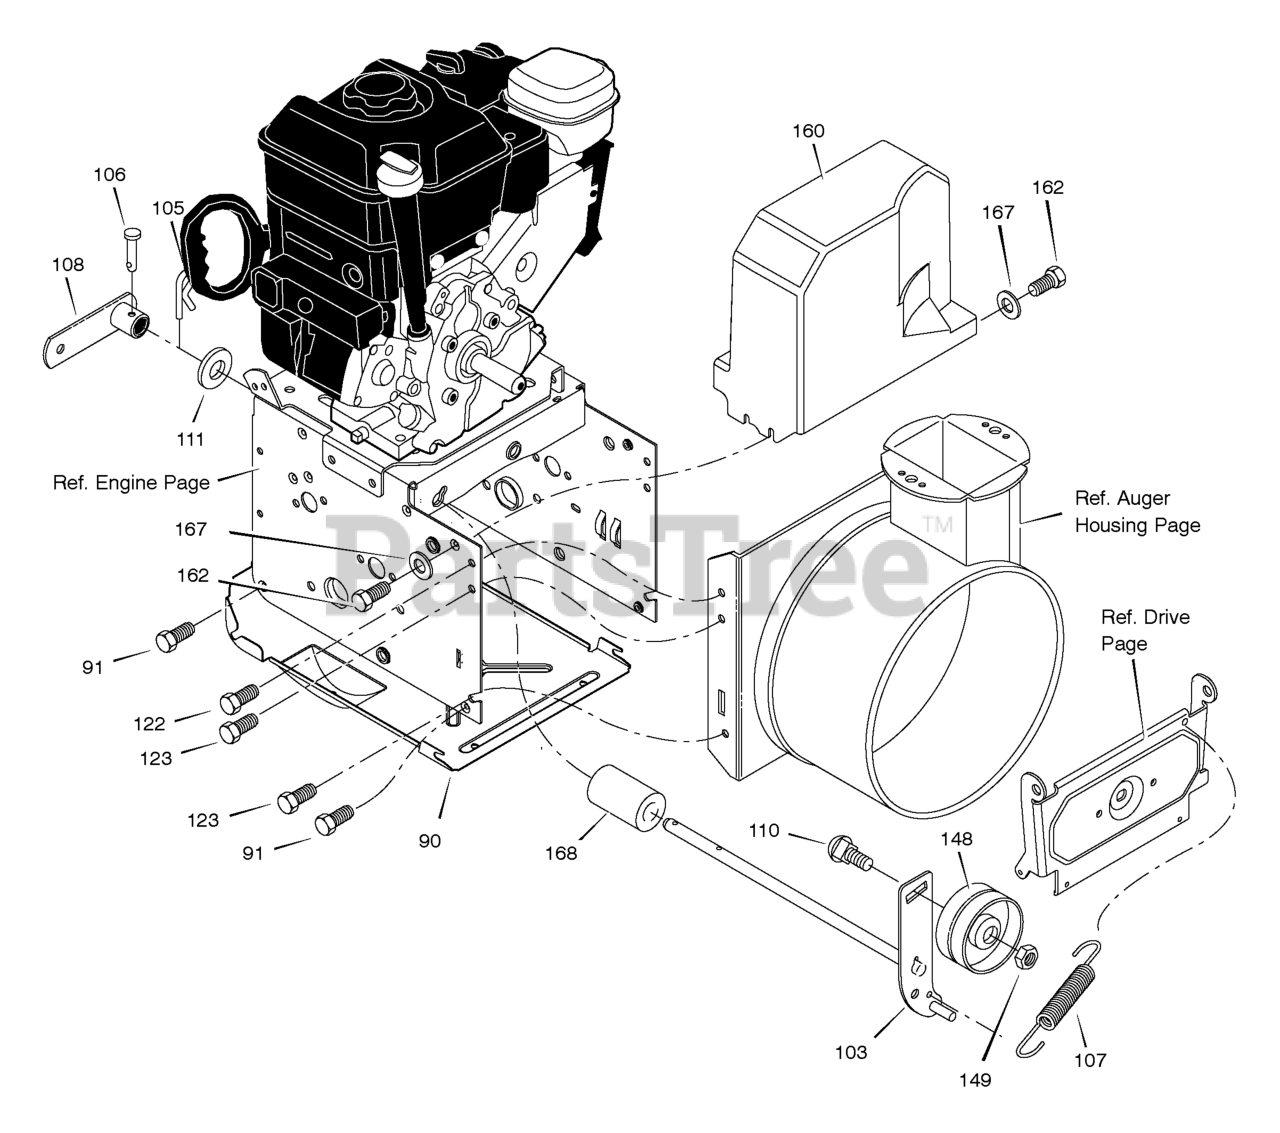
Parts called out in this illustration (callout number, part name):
90	COVER, BOTTOM
91	SCREW, 1/4-20X .63
103	IDLER ASSEMBLY, AUGER
105	PIN, HAIR .38DIAX1.64LG
106	PIN, CLEVIS 3/16" DIA
107	SPRING, TENSION
108	ASSY., SPRING ATTACH
110	BOLT, 3/8-16X1.25 CARR.
111	WASHER, FLAT
122	SCREW, TAP 5/16-18 X 0.50
123	SCREW, TAP 5/16-18 X 0.75
148	PULLEY, IDLER
149	NUT, JAM 3/8-16
160	COVER, BELT
162	SCREW, TAP
166	WASHER, FLAT
168	SPACER, AUGER BRACKET
